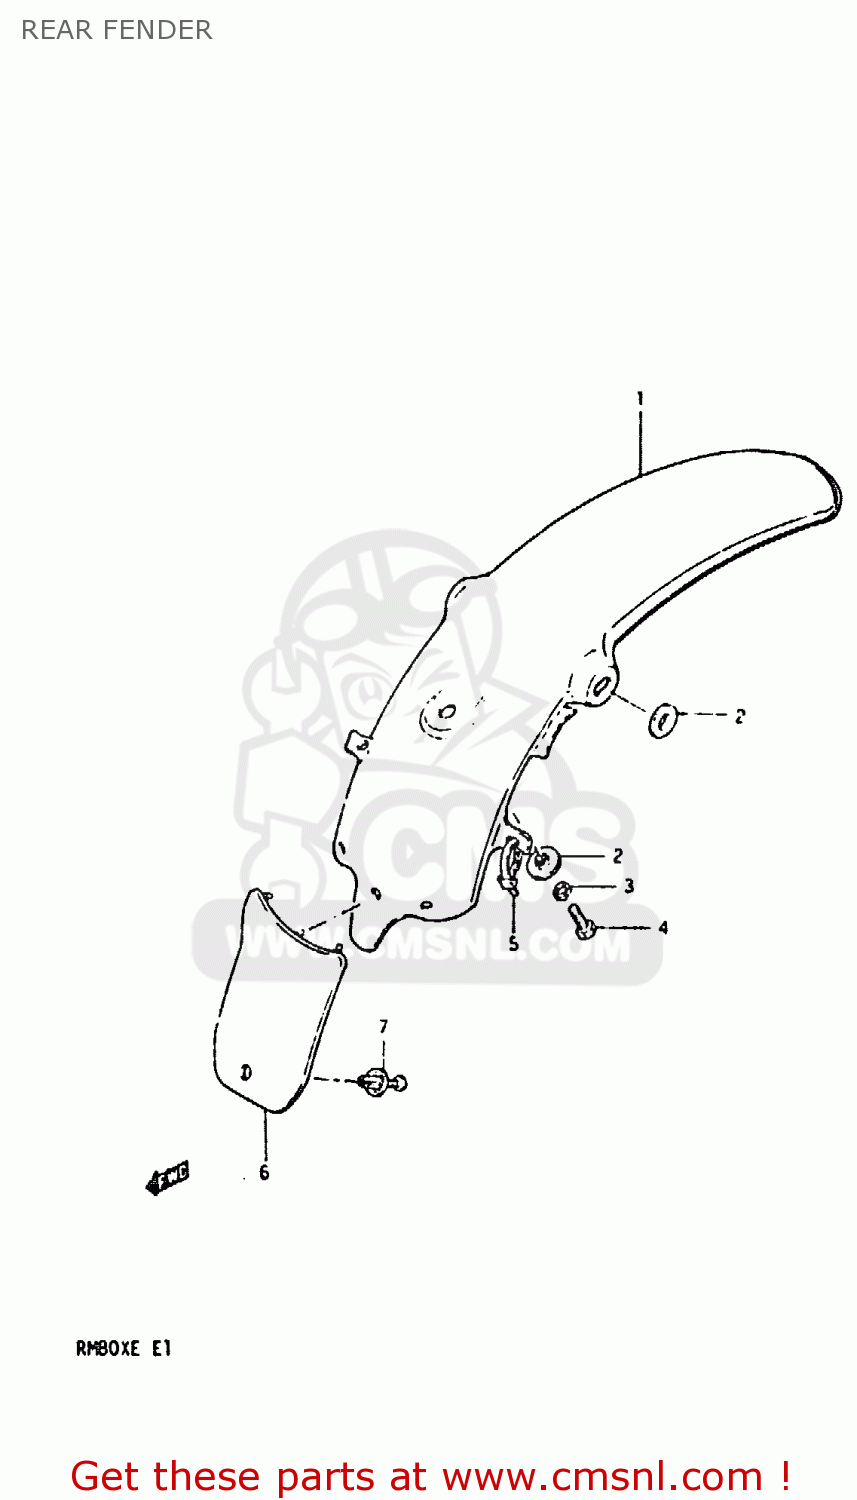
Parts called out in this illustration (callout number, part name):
1	FENDER,RR
2	WASHER
3	LOCK WASHER
4	BOLT, UPPER
5	CLAMP
6	GUARD,MUD
7	CLIP
